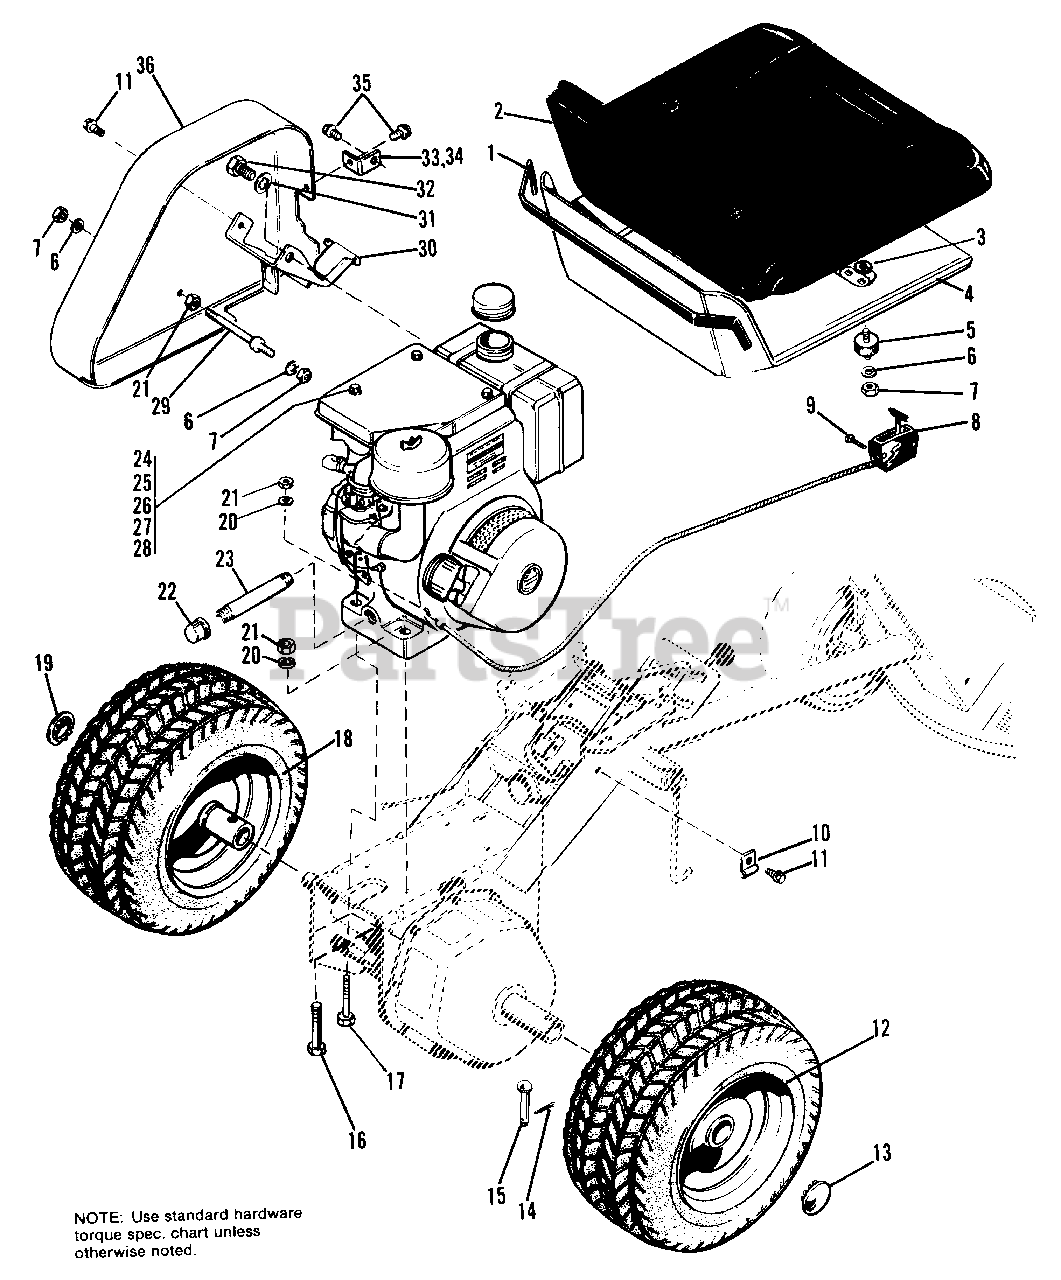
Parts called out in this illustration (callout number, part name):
1	TAPE, 2 ft.
2	PAD, Seat
3	WASHER, Plain, 5/16
4	PANEL, Seat
5	CONNECTOR, Cushion
6	LOCKWASHER, 5/16 (Qty. 6 used on 991020)
7	NUT, Hex, Full, 5/16-18 (Qty. 6 used on 991020)
8	CONTROL ASSY., Throttle
9	SCREW, Taptite, #10-24 x 1
11	SCREW, Taptite, 5/16-18 x 1/2
12	WHEEL & TIRE ASSY., Rear, R.H.
13	BUTTON, Plug
14	PIN, Cotter, 1/8 x 3/4
15	PIN
16	CAPSCREW, Hex Hd., 5/16-18 x 1-3/4
17	CAPSCREW, Special
18	WHEEL & TIRE ASSY., Rear, L.H.
19	BUTTON, Plug
20	WASHER, Plain, 5/16
21	LOCKNUT, Hex, 5/16-18
22	CAP, Pipe
23	NIPPLE, Pipe
24	SCREW, Taptite, Hex, 1/4-20 x 3/8
25	CAPSCREW, Hex Hd., 1/4-20 x 1-3/4
26	SHIELD, Heat
27	SUPPORT, Heat Shield
30	STOP, Belt
31	LOCKWASHER, Int. 1/2
32	CAPSCREW, Hex, 1/2-20 x 3/4
33	BRACKET, Pulley Guard
34	BRACKET, Pulley Guard
35	SCREW, Taptite, Hex, 5/16-18 x 3/8
36	GUARD, Pulley
